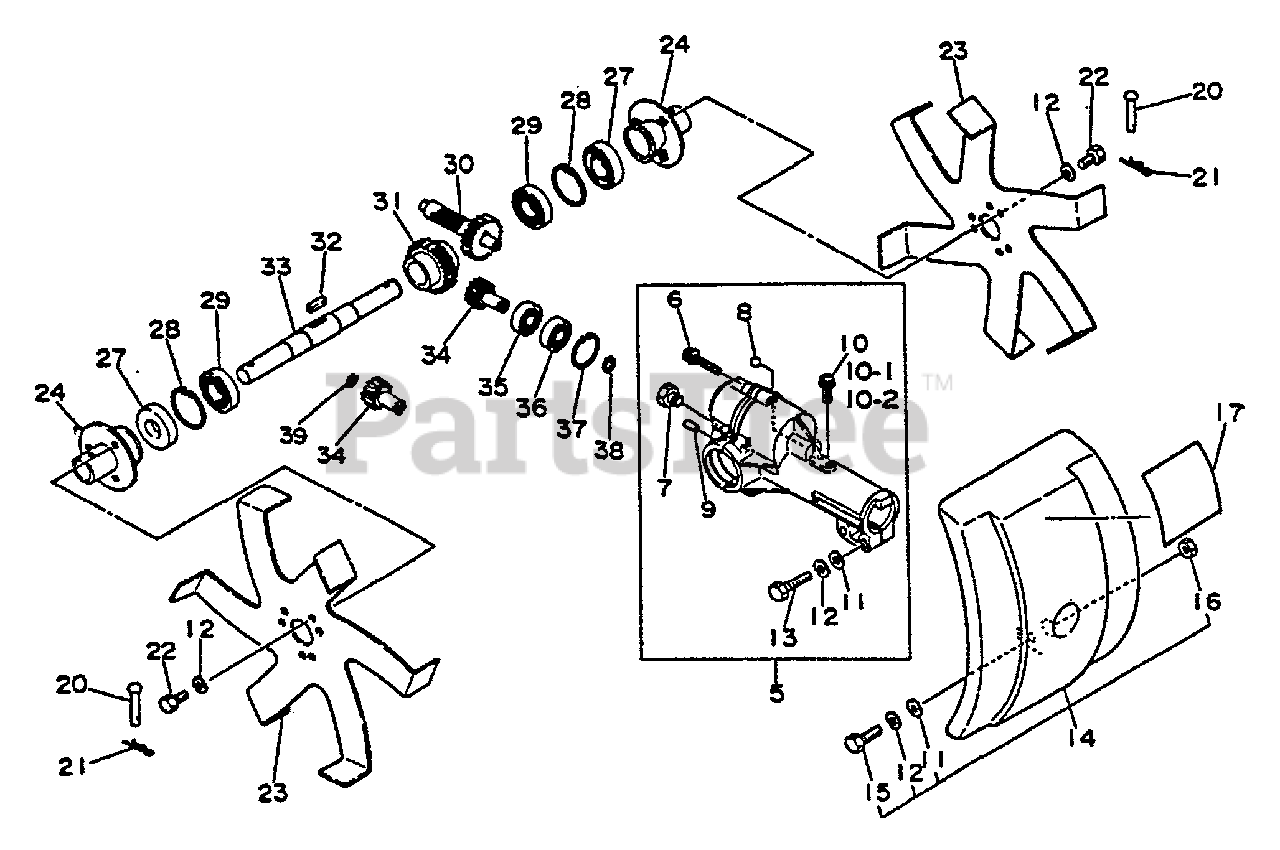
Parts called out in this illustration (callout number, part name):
5	CASE, GEAR
6	SCREW - 4X25
7	BOLT - 8X8
8	BALL, STEEL
9	PIN - LOCATING
10	SCREW - 5X14
10-1	LOCKWASHER - 5
10-2	WASHER - 5
11	WASHER - 6
12	LOCKWASHER - 6
13	BOLT - 6X25
14	SHIELD
15	BOLT - 6X20
16	LOCKNUT - 6
17	LABEL
20	PIN - CLEVIS
21	PIN, SPLIT
22	BOLT - 6X10
23	BLADE, CULTIVATOR
24	HUB, CLUTCH
27	SEAL, OIL - 17
28	RING, RETAINING - 30
29	BEARING, BALL - 6903
30	GEAR - DRIVE
31	WHEEL, WORM
33	SHAFT, WORM GEAR
34	GEAR
35	BEARING, BALL - 6001
36	BEARING, BALL - 6001Z
37	RING, RETAINING - 28
38	RING, RETAINING - 12
39	RING, RETAINING - 7
